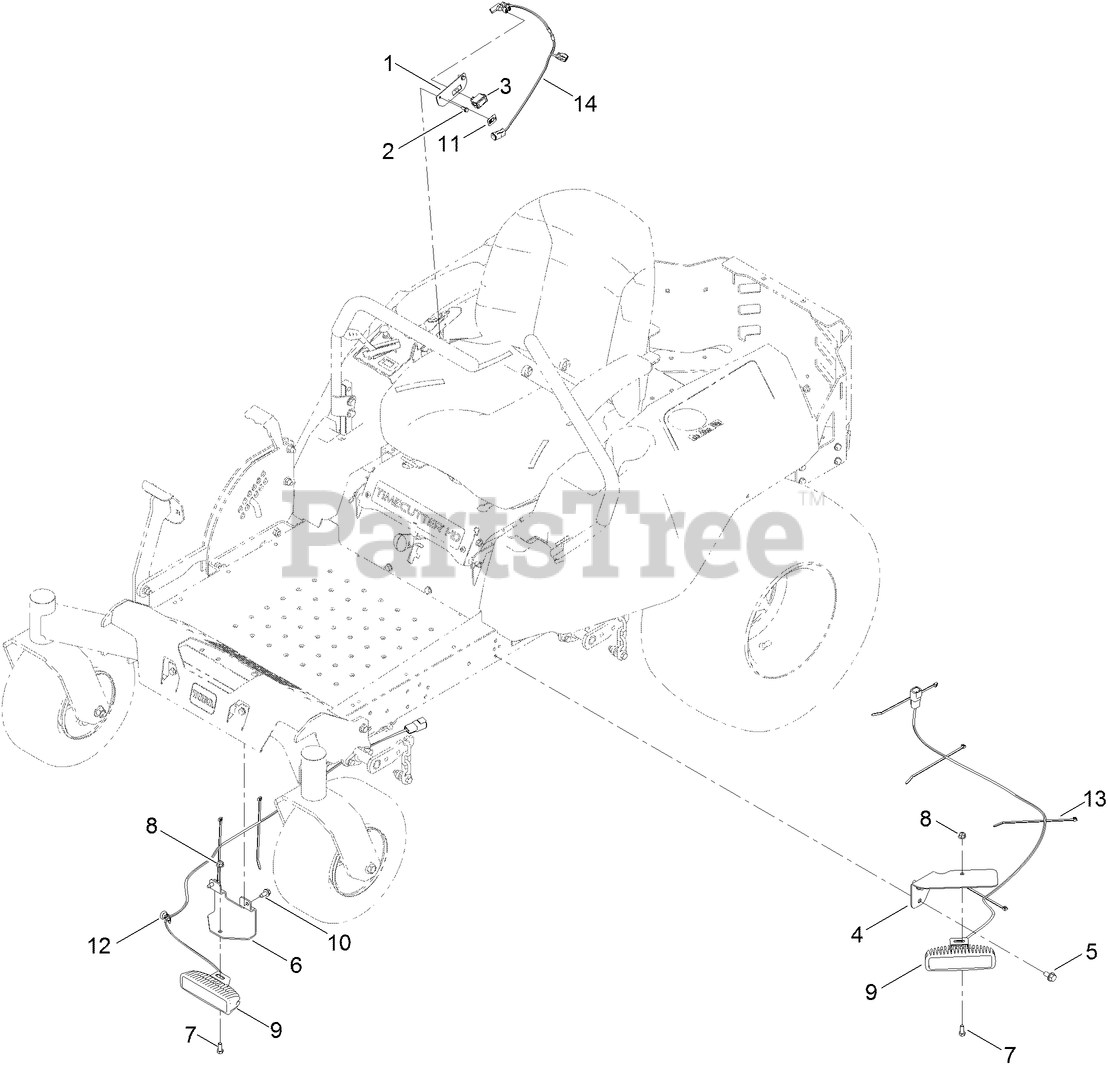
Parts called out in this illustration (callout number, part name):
1	BRACKET-SWITCH, LIGHT
2	SCREW-TAPTITE
3	SWITCH-ROCKER
4	BRACKET-LIGHT, SIDE
5	SCREW-HWH
6	BRACKET-LIGHT
7	SCREW-HH
8	NUT-HF, NI
9	LIGHT-LED
10	SCREW-HWHTF
11	DECAL-SWITCH, LIGHT
12	MOUNT-TIE WRAP, MAGNETIC
13	TIE-CABLE
14	HARNESS-WIRE
